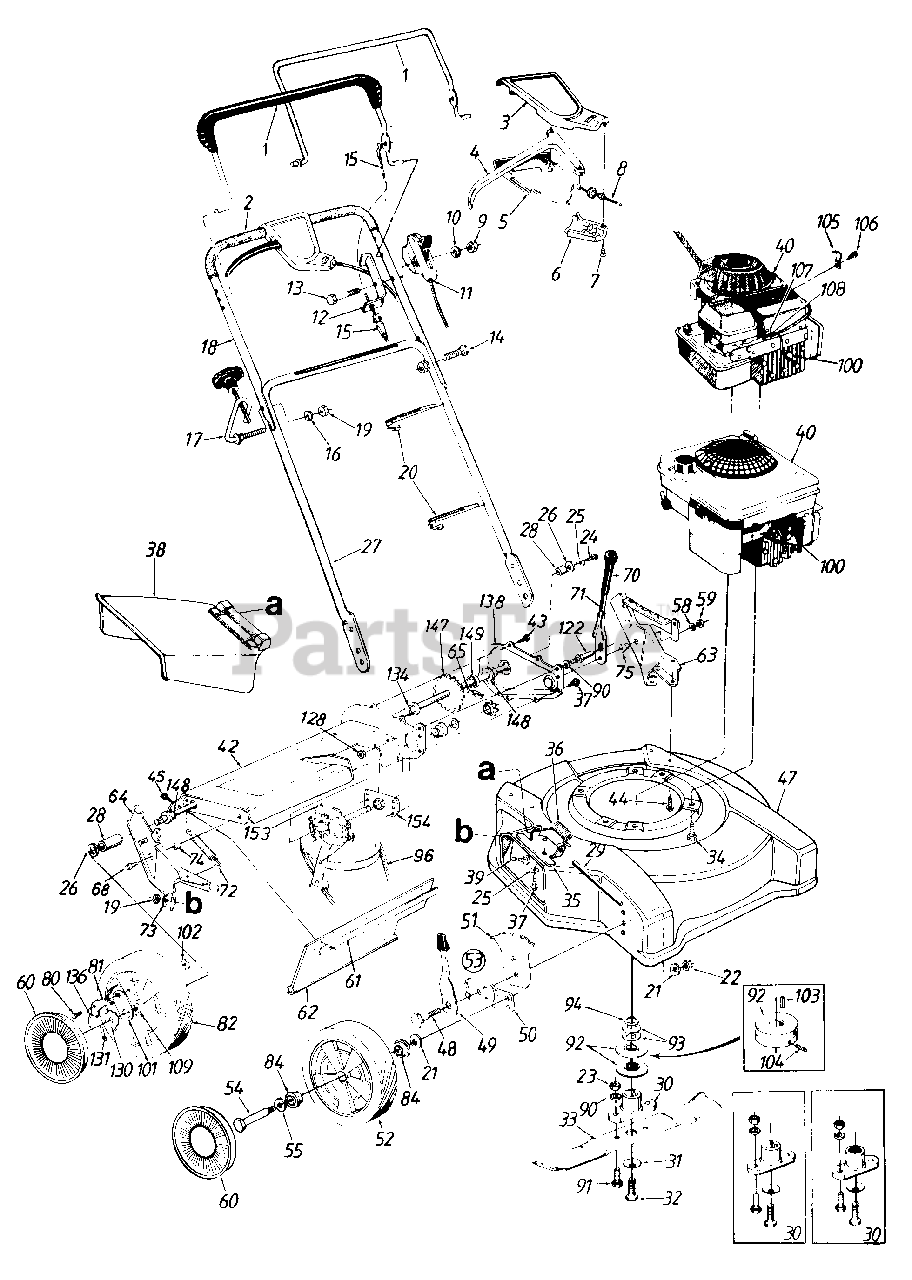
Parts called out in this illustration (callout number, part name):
1	Control Handle Ass'y
2	Foam Grip
3	Upper-S.P Control Cover
4	Control Lever
5	Lower-S.P. Control Cover
6	S.P. Control Cover
7	Fl-"C"-Sunk Hd. Tap Scr. #10 x . 75" Lg .
8	S.P. Adj. Cable x 48" Lg.
9	Hex Nut 1/4-20 Thd.
10	Spr. Wash. 265" I.D. x .562"
11	Throttle Control Ass'y. Comp. 56.6"
12	Cable Mtg. Brkt.
13	Hex Bolt 1/4-20 x 1.75" Lg.
14	Curved Carr. Bolt 5/16-18 x 1.38" Lg.
15	Control Cable 43" Lg.
16	L-Wash. 5/16" I.D.
17	Rope Guide Bolt
18	Upper Handle
19	Hex Nut 5/16-18 Thd.
20	Cable Tie
21	Bell-Wash. .38" I.D. x .88"
22	Hex Nut 3/8-16 Thd.
23	Hex Nut 3/8-24 Thd.
24	Hex Bolt 1/4-20 x .62" Lg. (Grade 5)
25	Bell-Wash. 1/4" I.D.
26	Fl-Wash. .531" I.D. x .93"
27	Lower Handle
28	Spacer .513" I.D. x .703"
29	Hinge Pin
30	Blade Adapter Kit
31	Bell-Wash. .39" I.D.
32	Hex Bolt 3/8-24 x 1.5" Lg.
33	22" Blade
34	Hex L-Wash. Hd. Scr. 3/8-16 x 1.0" Lg.
35	Adapter Plate
36	Torsion Spring
37	Hex Self-Tap Scr. 1/4-20 x .5" Lg.
38	Chute Deflector Ass'y.
39	Carriage Bolt 5/16-18 x .62" Lg.
40	Engine
44	Hex Wash. Hd. B-Tap Scr. 5/16-1 8
45	Hex AB-Tap Scr 1/4 x 62"
47	22" Deck Ass'y.
48	Shld. Bolt .5" Dia. x .357
49	Spring Lever Ass'y. w/Knob
51	Height Adj. Plate
52	Wheel Ass'y. Comp.
53	Height Adj. Ass'y. Comp.-R.H.
54	Shld. Bolt .498" Dia. x 1.45"
55	Wave Wash. .53" I.D. x .78"
58	Fl-Wash. .385" I.D. x .87"
59	Hex Patch L-Nut 3/8-24 Thd.
60	Hub Cap
61	Retaining Strip
62	Rear Flap
63	L.H. Handle Wheel Brkt. Ass'y.
64	R.H. Handle Wheel Brkt. Ass'y.
65	#48 Chain .500" Pitch x 30 Links
68	Hex Wash. Hd. Scr. 3/8-16 x 1.0" Lg.
71	Height Adj. Lever
72	Ext. Spring .5" O.D. x 3.8" Lg.
73	Bell-Wash. 5/16" I.D.
74	Spacer .383" I.D. x .503"
75	Shld. Spacer .5" Dia.
80	Shld. Scr. .342" Dia. x .268"
81	Pawl
82	Wheel Ass'y. Comp.
84	Ball Bearing 1/2" I.D.
90	L-Wash. 3/8" I.D.
91	Hex Bolt 3/8-24 x 1.0" Lg.
92	Keyed Pulley
93	Bell-Wash. 1.01" I.D.
94	Crankshaft Spacer
96	"V"-Belt
100	Spark Plug Boot
101	Pawl Plate
102	Weld Nut 1/4-20 Thd.
103	Sq. Key 3/16" x 3/4" Lg.
104	Set Scr. #10-32 x .25" Lg.
105	Cable Clamp
106	Hex B-Tap Scr. #10 x .38" Lg.
107	Cable Clamp
108	Hex B-Tap Scr. #10 x .5" Lg.
109	Sleeve Brg. 1/2" I.D.
122	Shld. Pin 3/8-24 x 1.43" Lg.
128	Hex Jam Nut 3/8-24 Thd.
130	Ratchet Wheel 1.62" O.D.
131	Cotter Pin 1/8" Dia.
134	Hex Flange Bearing
136	Spring-Nylon
148	Hex Flange Bearing
149	Fl-Wash. .531" I.D. x .93"
153	Transmission Comp.
